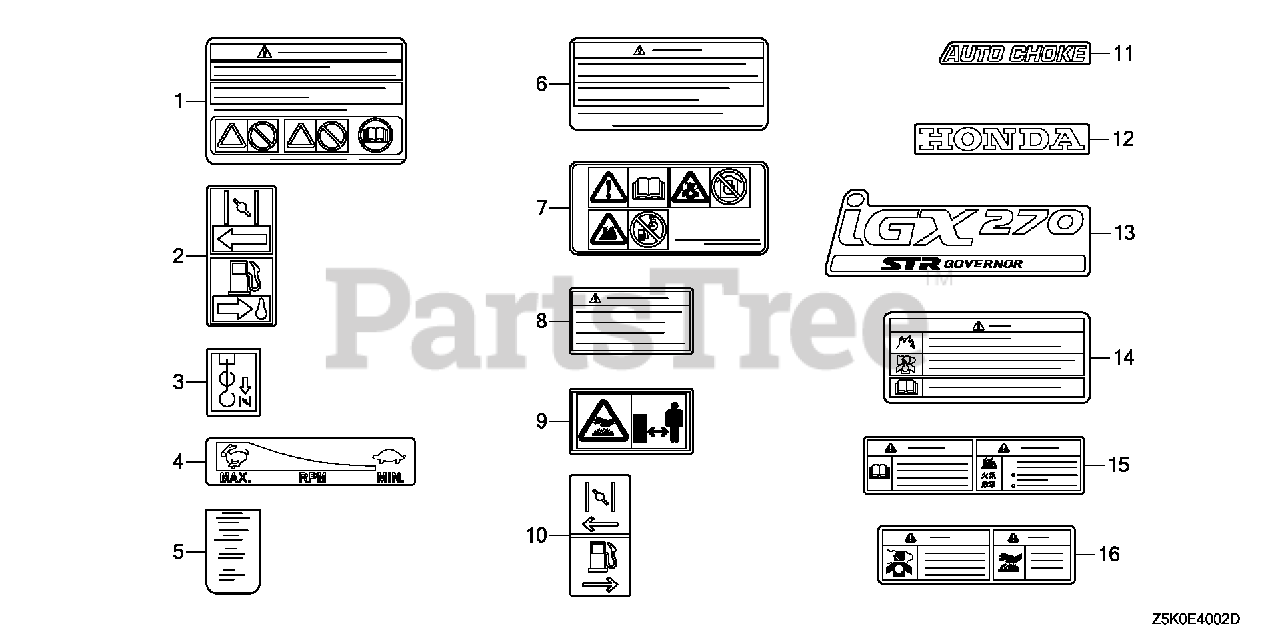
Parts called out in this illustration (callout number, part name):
6	MARK, OPERATOR CAUTION (FRENCH)(MADE IN THAI)
7	MARK, OPERATOR CAUTION (PICTOGRAPH)
8	MARK, EX. CAUTION (FRENCH)
9	MARK, EX. CAUTION (PICTOGRAPH)
